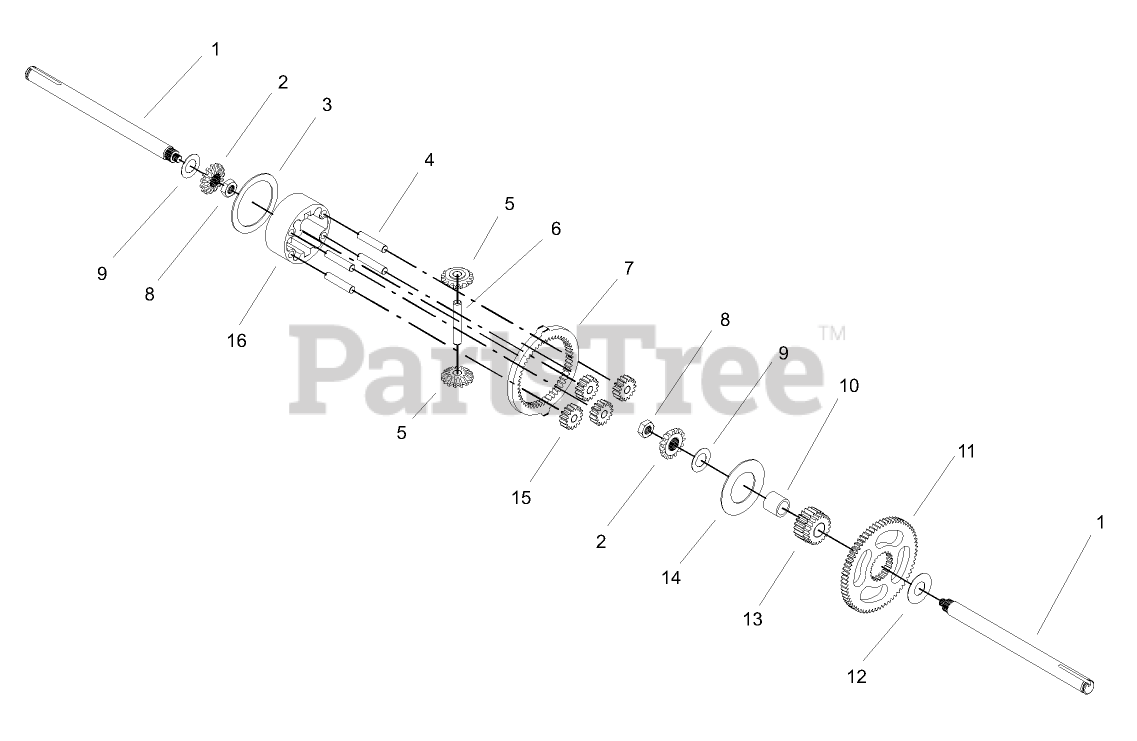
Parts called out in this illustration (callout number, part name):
1	SHAFT-AXLE
2	GEAR-MITER
3	PLATE-THRUST
4	PIN-CARRIER
5	GEAR-MITER
7	GEAR-RING, 51T
8	NUT-HJ
9	WASHER
10	BEARING-SLEEVE
11	GEAR-SPUR, 67T
12	WASHER
13	GEAR-SUN, 21T
14	PLATE-THRUST, PLANET
15	GEAR-PLANET, 15T
16	CARRIER-PLANETARY
